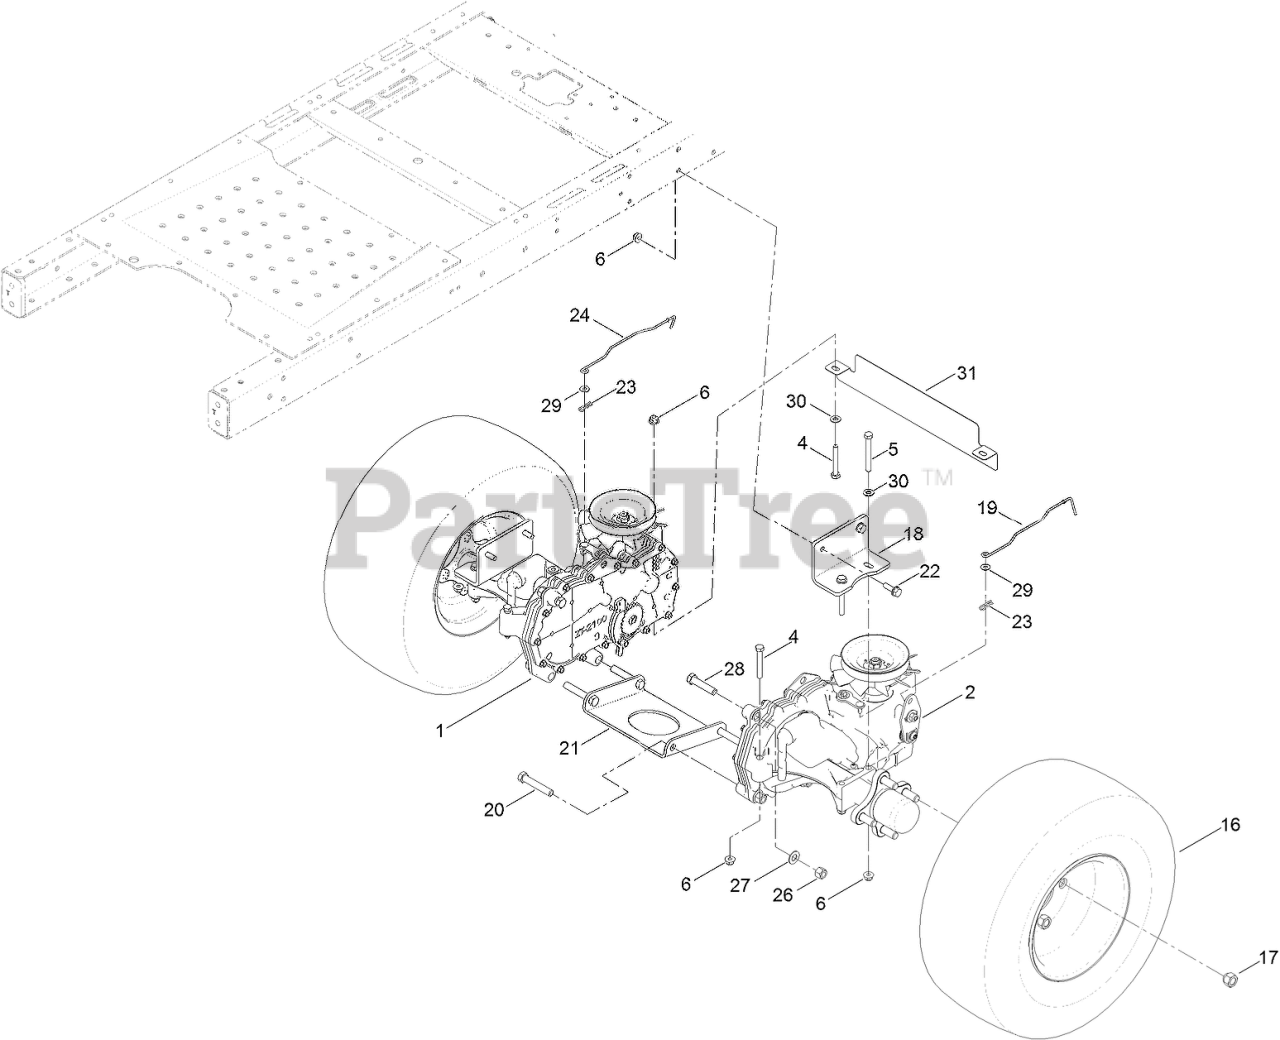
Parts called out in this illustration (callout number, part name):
1	RH HYDRO TRANSAXLE ASM
2	LH HYDRO TRANSAXLE ASM
4	SCREW-HH
5	SCREW-HH
6	NUT-HF, NI
16	2 PLY TIRE AND WHEEL ASM
17	NUT-LUG
18	MOUNT-HYDRO
19	ROD-BYPASS, LH
20	SCREW-HH
21	PLATE-CROSS, HYDRO
22	SCREW-HHF
23	PIN-COTTER
24	ROD-BYPASS, RH
26	NUT-LOCK, NI
27	WASHER-FLAT
28	SCREW-HH
29	WASHER
30	WASHER-PLAIN
31	GUARD REAR, NARROW
